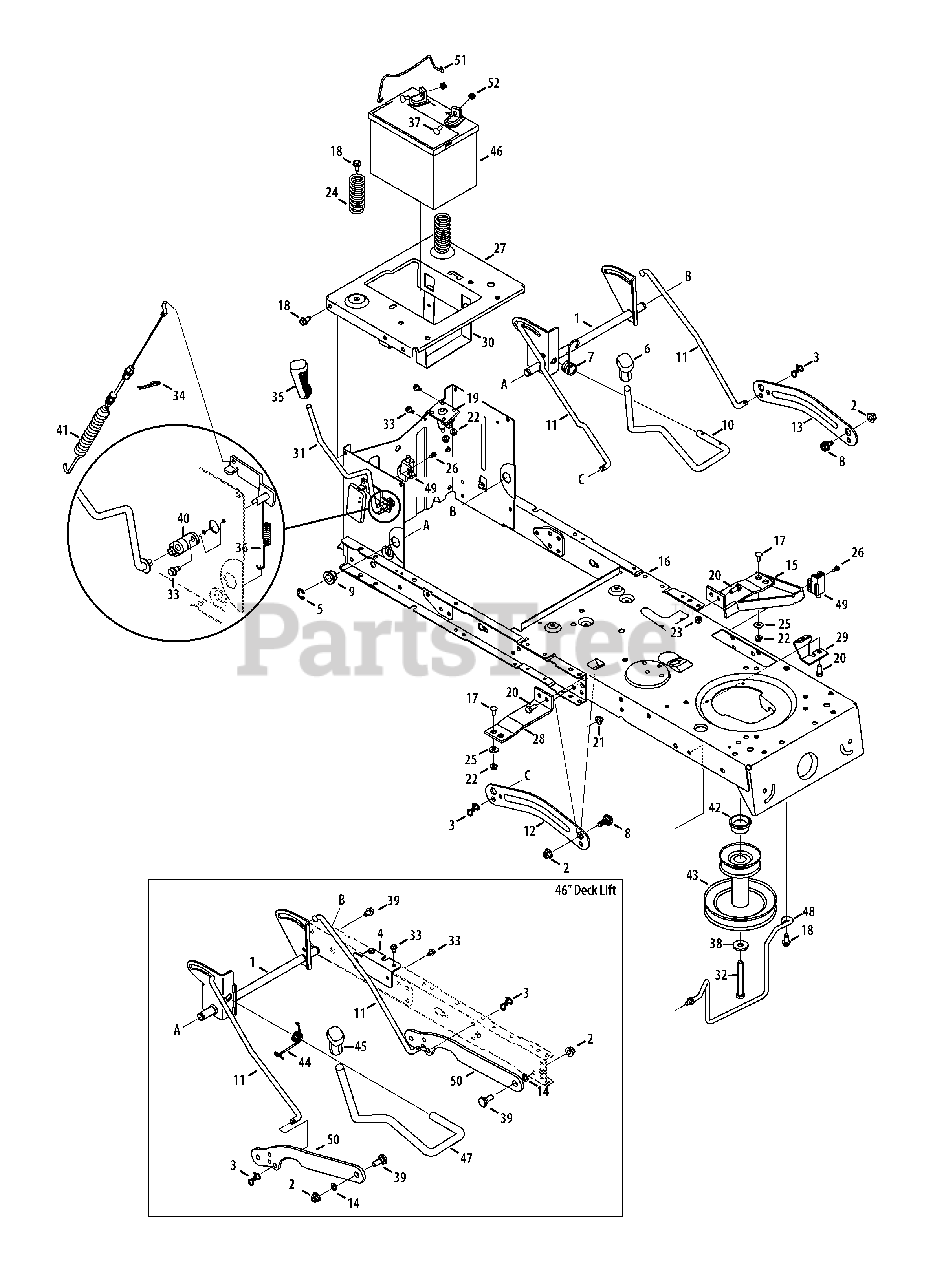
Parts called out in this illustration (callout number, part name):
1	Shaft Assembly Lift 46" Deck
2	Nut, Flange Lock, 3/8-16, GrF
3	Pin, Cotter, Bow Tie
4	Frame Brace Bracket
5	Ring, E-Type, .625 Dia.
6	Grip, Handle, 1/2
7	Spring, Torsion 42" Deck
8	Screw, Shoulder, .625 x .175, 3/8-16
9	Bearing, Hex Flange
10	Deck Handle, Lift, 42" Deck
11	Rod, Lift
12	Lift Arm, Deck - RH
13	Lift Arm, Deck - LH
14	Washer, Flat, .385 x .62 x .063
15	Support Bracket Assembly
16	Frame Assembly
17	Carriage Screw, 1/4-20 x .62
18	Screw, 5/16-18, .750
19	Solenoid
20	Hex Screw, 5/16-18 x .75
21	Flange Lock Nut, 5/16-18
22	Nut, Flange Lock, 1/4-20, GrF
23	Hex Lock Nut, 5/16-18
24	Spring, Compr. , 1.28 OD x 3.125
25	Flat Washer, .28 x .74 x .063
26	Shoulder Screw, #10-32 x .500
27	Seat Bracket, Frame
28	Bracket, Runing Board
29	Frame Support Bracket
30	Bracket, Battery
31	Handle Assembly, PTO
32	Hex Screw, 7/16-20 x 3.25
33	Screw, 1/4-20, 0.500
34	Pin, Click, .092 x 1.64
35	Grip, Handle, 3/8
36	Spring, Extension
37	Screw, Carriage, 1/4-20, .75, Gr5
38	Washer, Flat, .450 x 1.250 x .164
39	Bolt, Shldr. .500 x .270 3/8-16
40	Bearing, PTO
41	Cable, Deck Engagement
42	Spacer, 1.010 x 1.400 x .825, 42" Deck
43	Engine Pulley
44	Spring, Torsion 46" Deck
45	Grip, Handle, 5/8
46	Battery, 155 CCA
47	Deck Handle, Lift, 46" Deck
48	Rod, Belt Keeper (46" Deck)
49	Switch, Interlock
50	Deck Lift Link
51	Battery Hold Down Rod
52	Nut, Sems, 1/4-20
